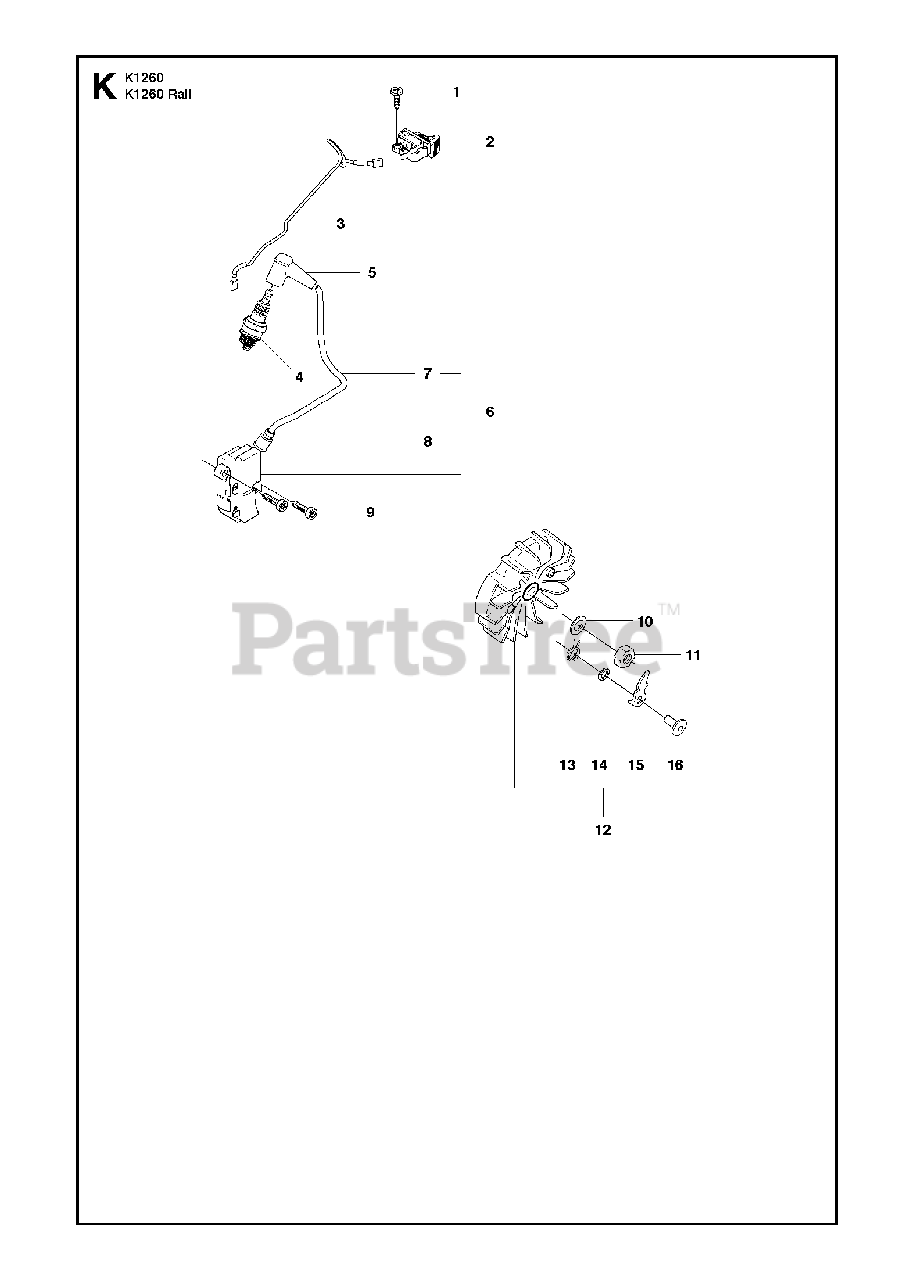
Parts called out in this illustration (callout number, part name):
1	SCREW CCRPANT
2	STOP SWITCH
5	SPARK PLUG CAP
6	IGNITION MODULEIncl. 7 - 8
7	IGNITION CABLE
9	SCREW ITXSCM
10	SPRING WASHER
12	FLYWHEEL ASSYIncl. 13 - 16
16	SCREW
